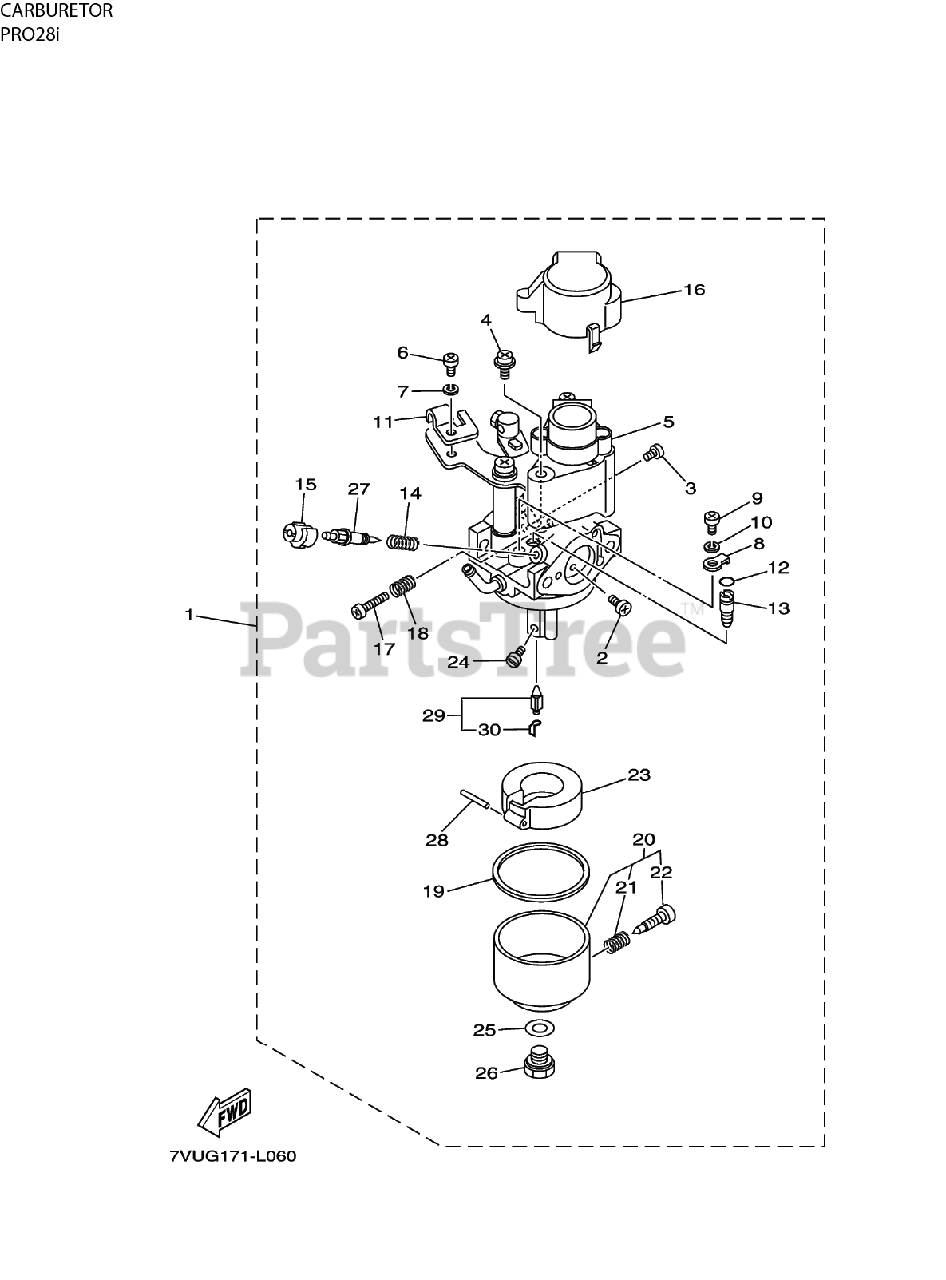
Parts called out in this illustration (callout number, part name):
1	CARBURETOR ASSEMBLY
4	SCREW - BOLT
5	MOTOR ASSEMBLY
7	WASHER USE 33 468 18-S
13	JET, MAIN (#41.3)
16	COVER, AIR CLEANER
17	SCREW - THROTTLE
19	GASKET, FLOAT CHAMBER
20	BOWL, FUEL - BODY FLOAT CHAMBER
24	JET, MAIN (#91.3)
26	SCREW - HOLDING
27	SCREW - BOLT
28	PIN, FLOAT
29	NEEDLE ASSEMBLY
